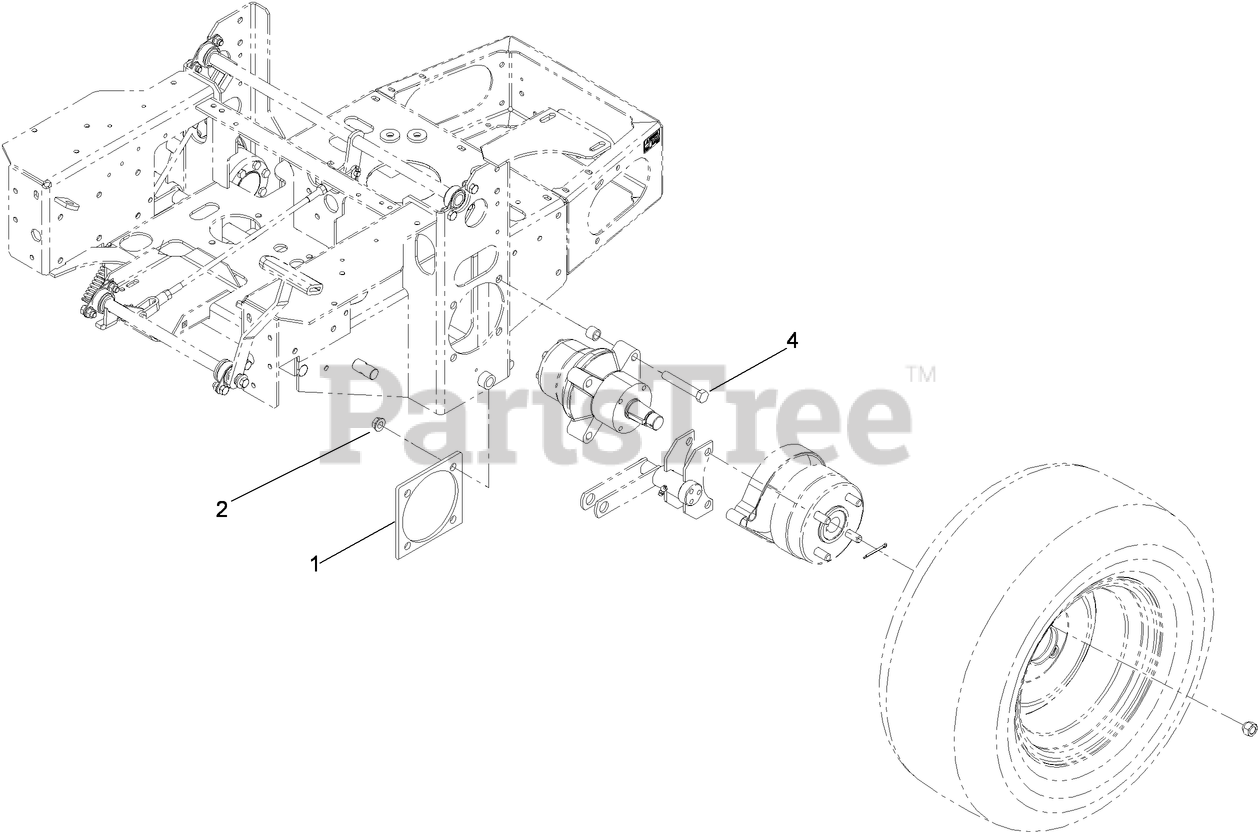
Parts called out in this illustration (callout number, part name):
1	PLATE-REINFORCEMENT
2	NUT-HHF
4	SCREW-HH
